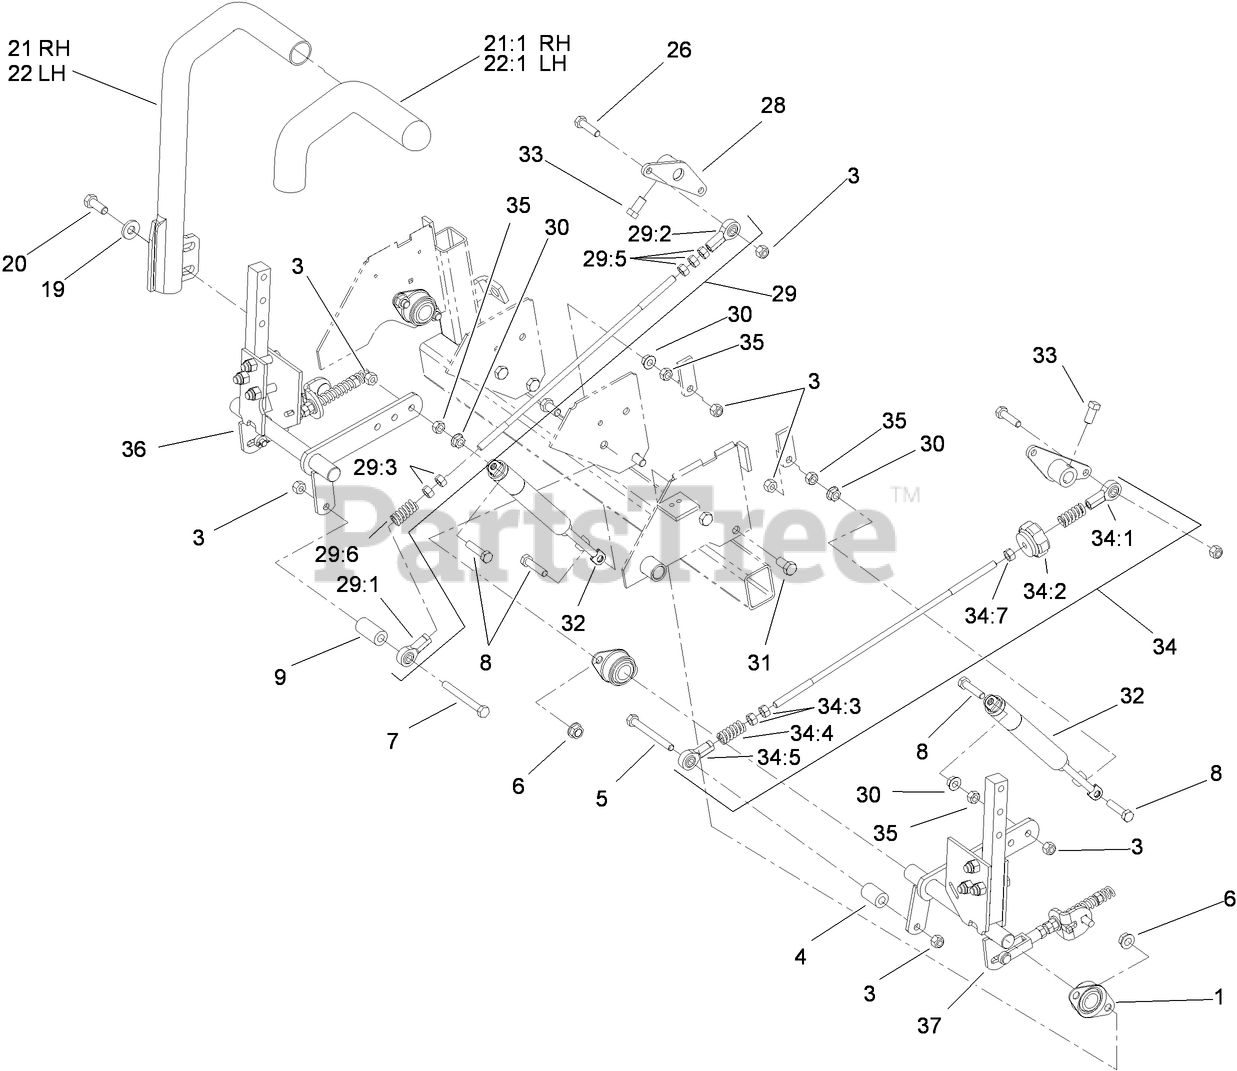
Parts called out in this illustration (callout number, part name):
1	BEARING-FLANGE, SIDE
3	NUT-LOCK, NI
4	SPACER-HYDRO CONTROL, LH
5	SCREW-HH
6	NUT-HHF, WHIZ
7	SCREW-HH
8	SCREW-HH
9	SPACER-CONTROL, HYD
19	WASHER-BELLEVILLE
20	SCREW-HH
21	RH LEVER ASM
21:1	Grip-Control, Motion
22	LH LEVER ASM
22:1	Grip-Control, Motion
26	SCREW-HH
28	ARM-CONTROL, HYDRO
29	RH HYD CONNECT LINK ASM
29:1	BALLJOINT-RH
29:2	BALLJOINT-LH
29:5	NUT-HEX
29:6	SPRING-COMPRESSION
30	NUT-HF
31	SCREW-HH
32	DAMPER-CONTROL, MOTION
33	SCREW-SET
34	TRACKING ROD ASM
34:1	BALLJOINT-RH
34:2	KNOB-TRACKING
34:4	SPRING-COMPRESSION
34:5	BALLJOINT-LH
34:7	NUT-HEX
35	NUT-HEX
36	RH MOTION CONTROL ASM
37	LH MOTION CONTROL ASM
